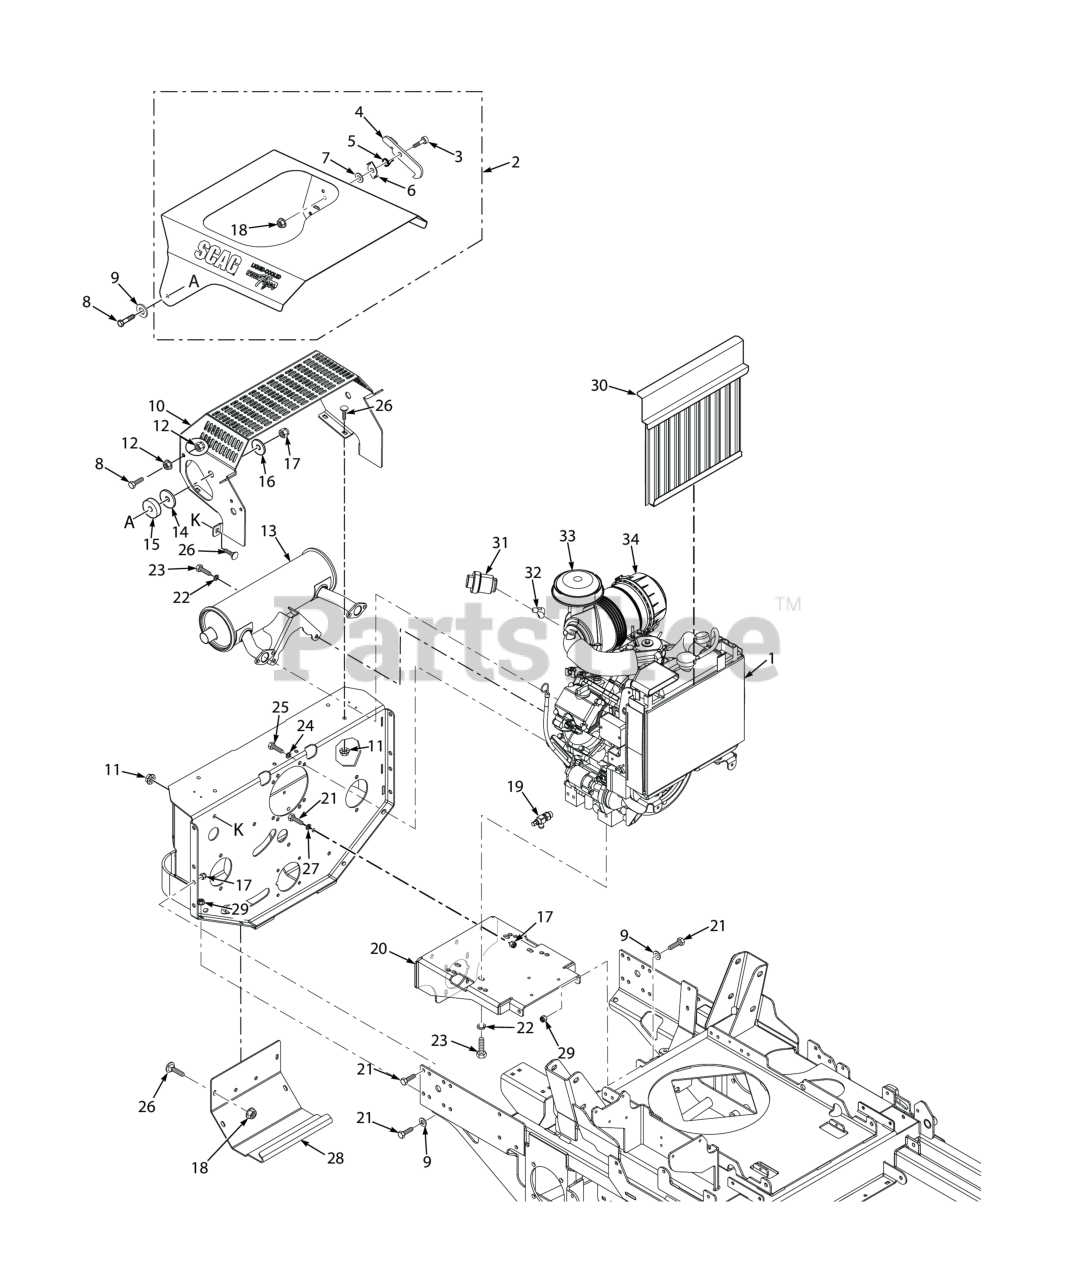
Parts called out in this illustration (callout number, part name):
1	Engine, FD850 - Kawasaki
2	Hood Assy., STTII (FD791 & FD850) - Fuel Injected
3	Bolt, Shoulder 5/16-18 x 1/2"
4	Latch, Hood
5	Spring, Hood Latch
6	Lock, Hood Latch
7	Flatwasher, 3/8 (.406 x .812 x .065)
8	Bolt, Hex Head 3/8-16 x 1-3/4" (Kohler EFI)
9	Flatwasher, 3/8" Special (.391 x .938 x .105)
10	Guard, Muffler
11	Nut, Flange Head Elastic Stop 5/16-18
12	NUT, 3/8-16 SERRATED FLANGE HEX HEAD
13	Muffler (Kawasaki)
14	Disc, Anti-Friction
15	Spacer, Hood
16	Flatwasher, 3/8-.406 x 1-1-1/2 x 7 Gauge
17	HEX NUT, ELASTIC STOP LOCK, 3/8-16
18	Nut, Serrated Flange 5/16-18 (Right Front Engine Mounting, Briggs and Kohler Only)
19	Oil Drain, 2.6" (Kawasaki Only)
20	Plate Weldment, Engine Mounting
21	Bolt, Hex Head, 3/8-16 x 1 Gr. 5
22	Lockwasher, 7/16� Spring
23	Bolt, Hex Head M10-1.5 x 25 fULL Thread
24	Lockwasher, 5/16 (.317 x .586 x .078) Helical Spring
25	Bolt, Metric Hex Head M8-1.25 x 20LG
26	Bolt, 5/16-18 x .75 RHSN Carriage
27	Lockwasher, 3/8" Spring, Kawasaki FX / FT & FT-EFI / B&S 32BV
28	Cover, Rear
29	Nut, Flange Elastic Stop Nut, 3/8-16
30	Screen Weldment, Radiator (Kawasaki Only)
31	Gauge, Pressure Indicator
32	ELBOW, 90 DEGREE NPT
33	Rain Bonnet
34	Air Cleaner Assy. KA/DFI (INCL. 31,32,33)
